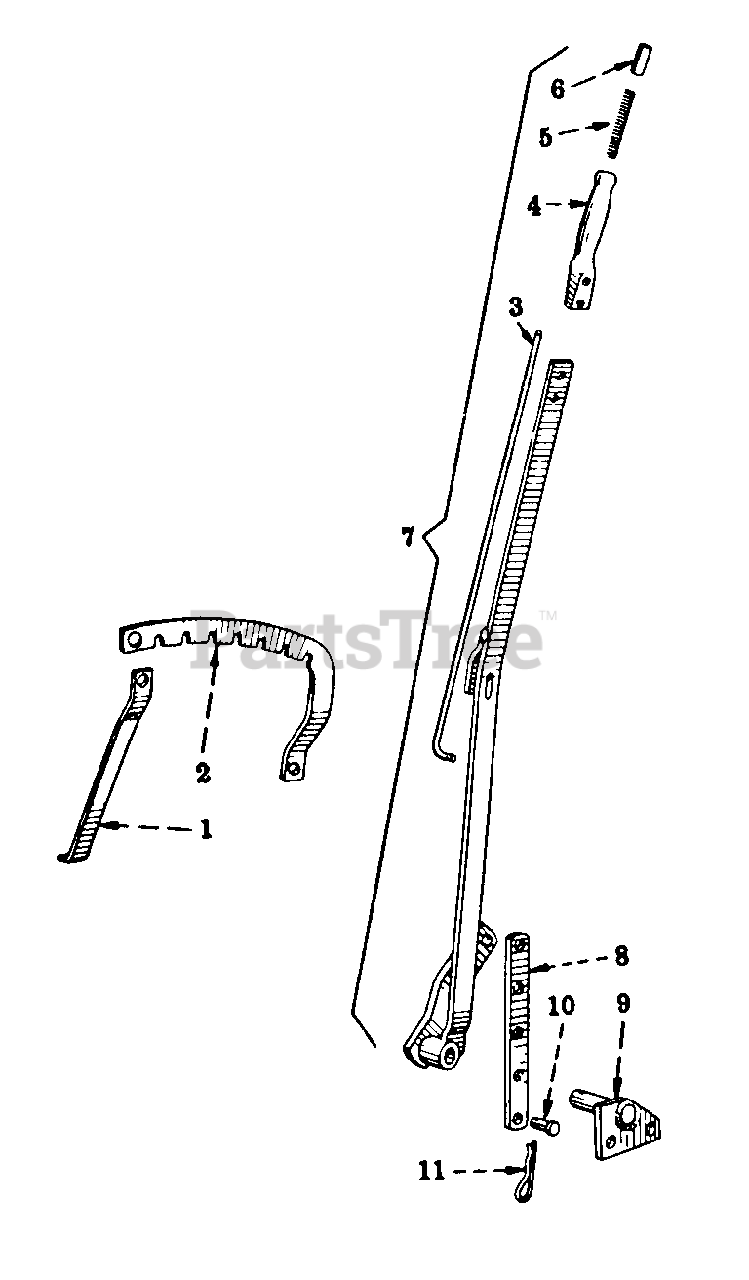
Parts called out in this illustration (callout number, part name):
1	BRACE, QUADRANT
2	QUADRANT, ADJUSTING LEVER
4	HANDLE, ADJUSTING LEVER
5	SPRING, PUSH BUTTON
6	BUTTON, PUSH
7	LEVER ASSY, ADJUSTING -COMPOSED OF THE FOLLOWING 10 PARTS
8	LINK, LEVER ARM
9	PLATE ASSY, LEVER PIVOT
10	PIN, LEVER LINK LOWER
11	PIN, 3/16 QUICK-ATTACHABLE COT.
